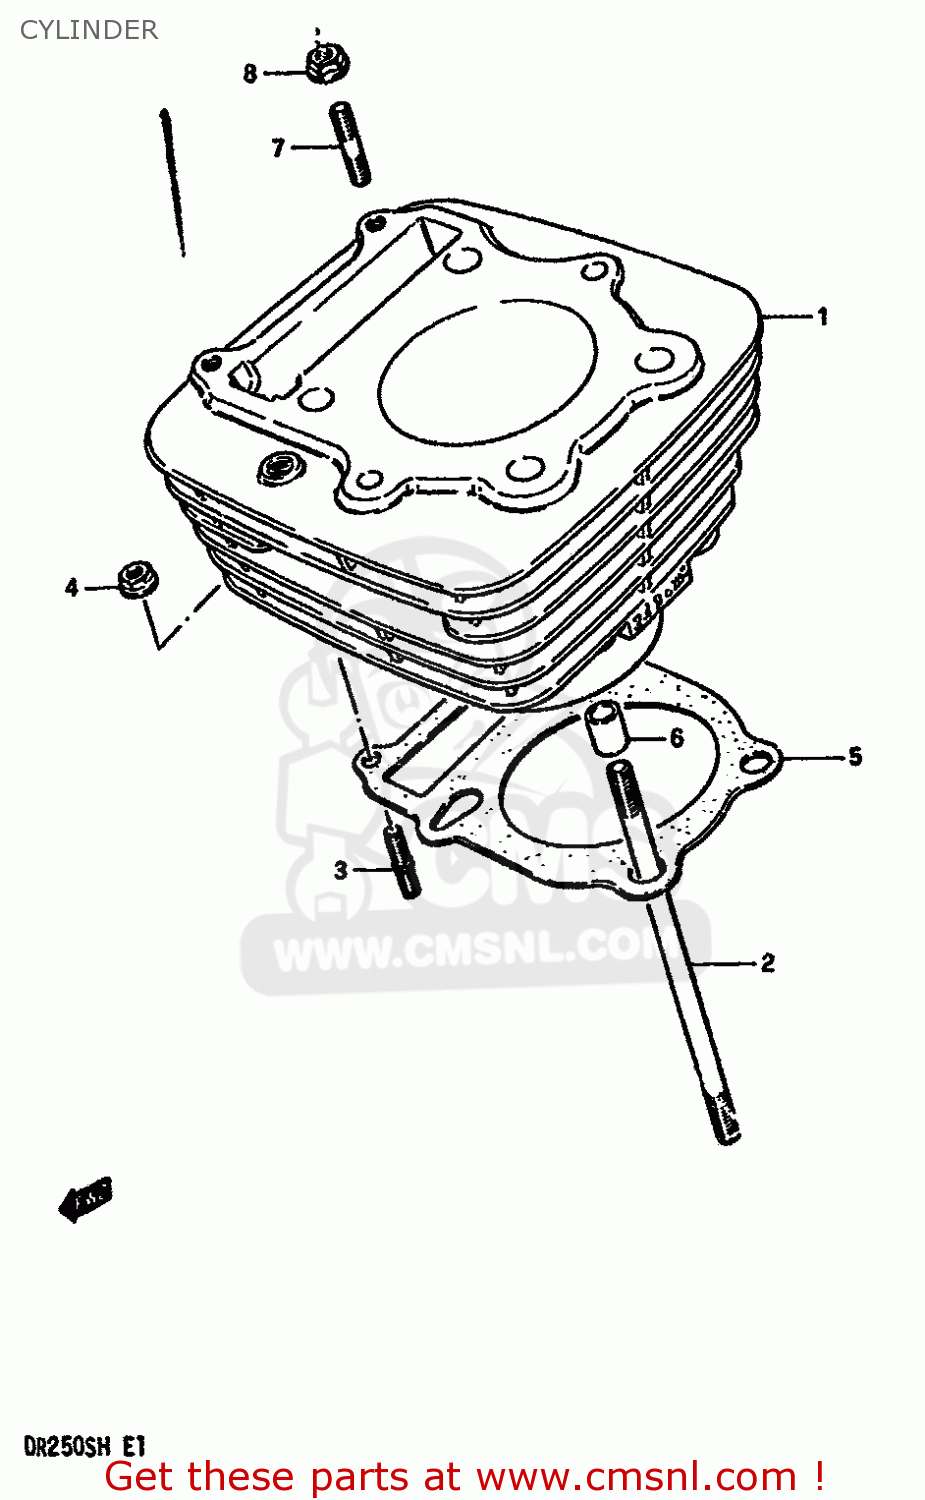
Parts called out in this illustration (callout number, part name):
1	CYLINDER
2	BOLT,STUD
3	STUD 6X25
4	NUT 6MM
5	GASKET,CYLINDER (MCA)
6	PIN
7	BOLT (6X30)
8	NUT 6MM
